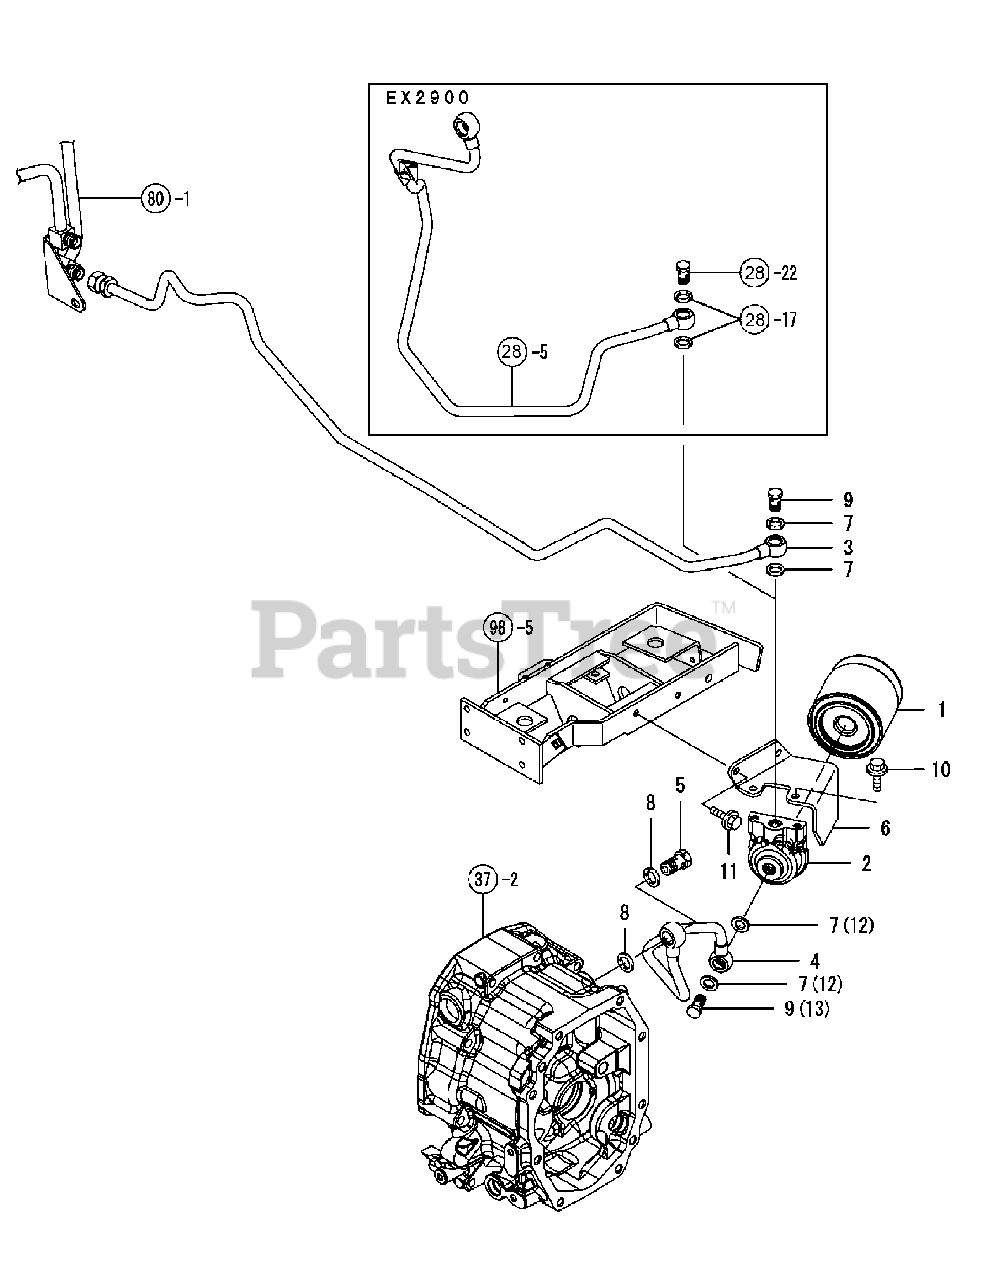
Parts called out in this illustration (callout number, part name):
3	LINE ASSY, FILTER
4	LINE ASSY, FILTER-HST - S/N F000155 & BELOW
4	LINE ASSY, FILTER-HST - S/N F000156 & ABOVE
5	CONNECTOR ASSY
6	BRACKET, FILTER
10	BOLT M 8X 16 PLATED
11	BOLT M 8X 12 PLATED
